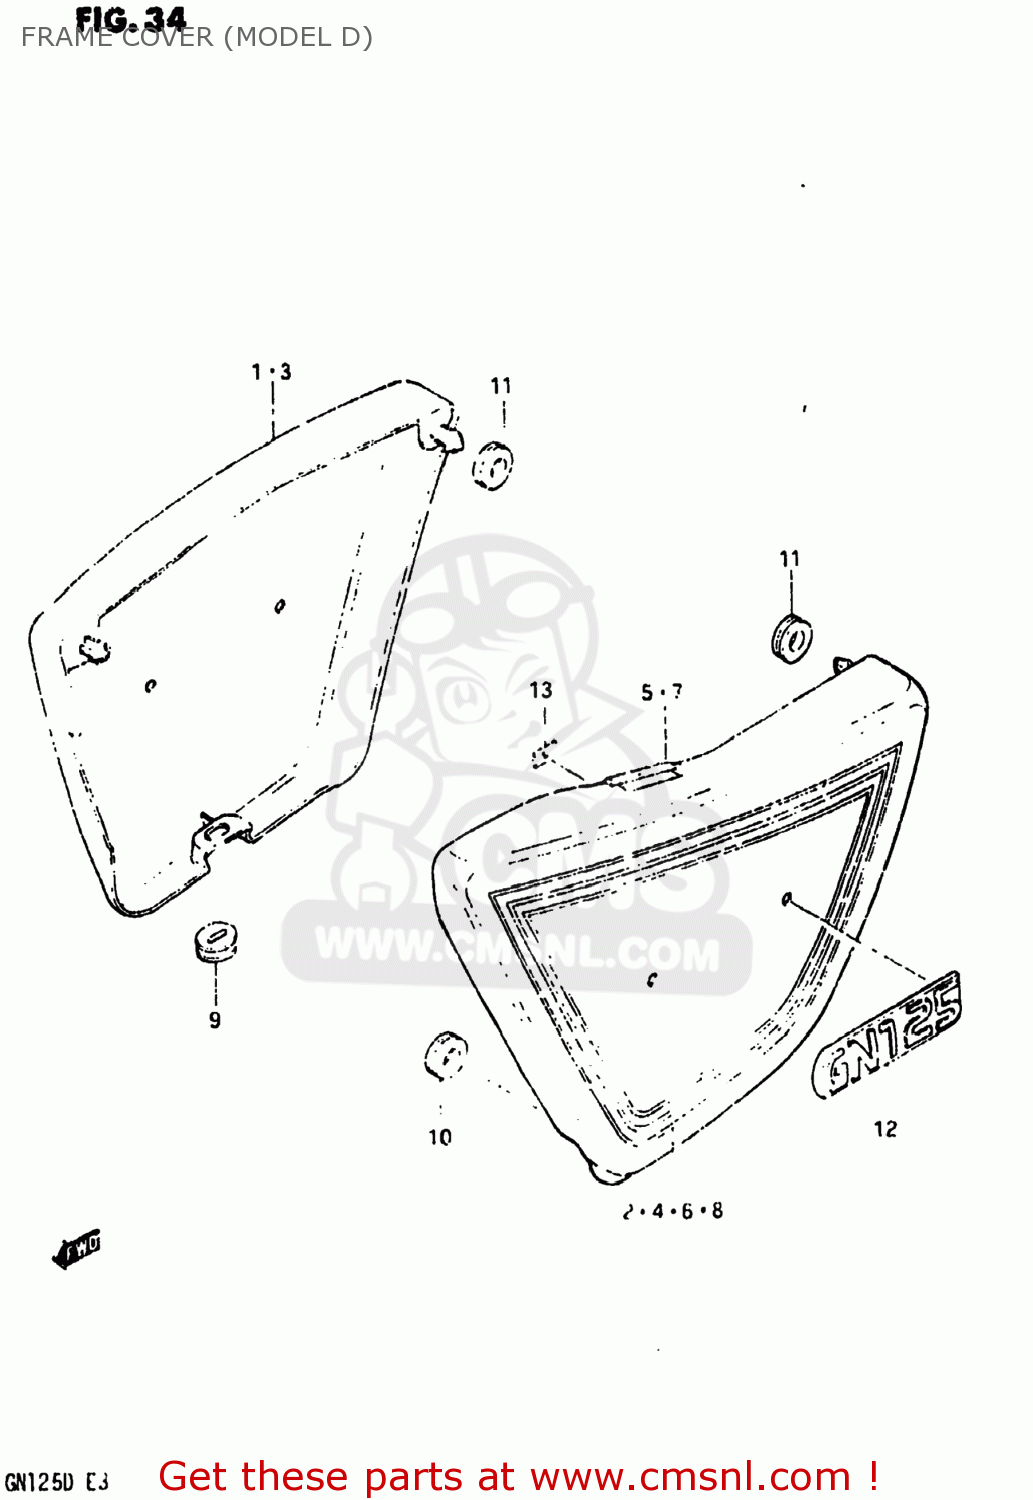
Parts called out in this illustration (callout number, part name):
1	COVER,FRAME,RIGHT
2	TAPE SET,FRAME COVER
3	COVER,FRAME,RIGHT
4	TAPE SET,FRAME COVER,RIGHT
5	COVER,FRAME,LEFT
6	TAPE SET,FRAME COVER
7	COVER,FRAME,LEFT
8	TAPE SET,FRAME COVER,LEFT
9	CUSHION
10	CUSHION
11	CUSHION
12	EMBLEM,FRAME COVER
13	NUT
